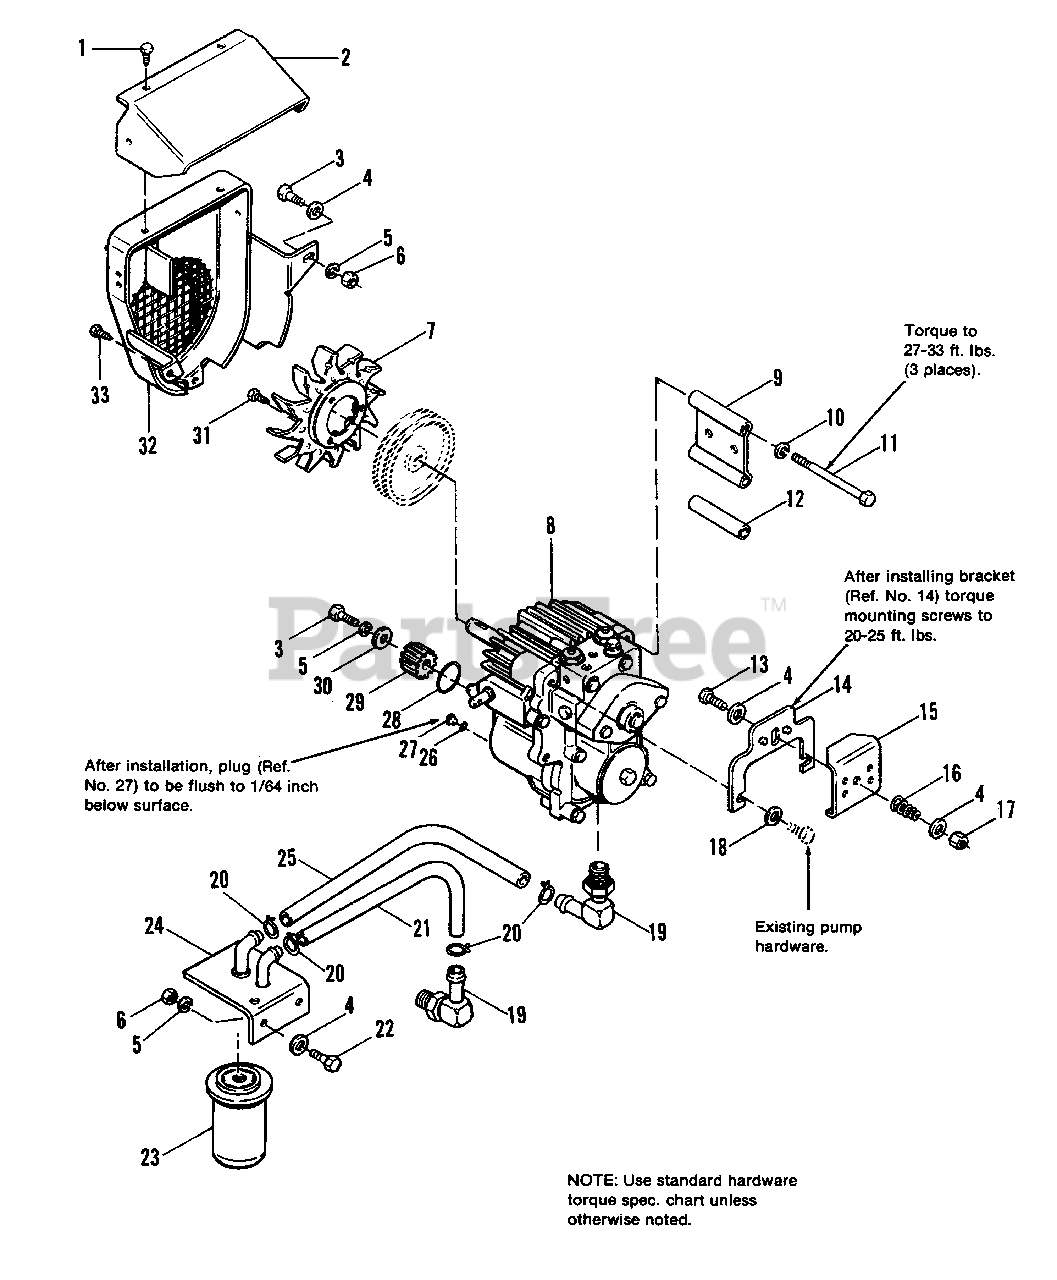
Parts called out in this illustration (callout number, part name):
1	SCREW, Self Tapping, #10 x 3/8
2	DEFLECTOR, Shroud
3	CAPSCREW, Hex Hd., 5/16-18 x 3/4
4	WASHER, Plain, 5/16
5	LOCKWASHER, 5/16
6	NUT, Hex, Full, 5/16-18
7	FAN, Pulley
8	HYDROSTATIC PUMP & MOTOR UNIT (7112 & 7114)
8	HYDROSTATIC PUMP & MOTOR UNIT (7116, 7117 & 7119)
10	LOCKWASHER, 3/8
11	CAPSCREW, Hex Hd., 3/8-16 x 5
12	SPACER
13	CAPSCREW, Hex Hd., 5/16-18 x 1
15	LATCH, Release
17	LOCKNUT, Hex, 5/16-18
19	FITTING, Hose
20	CLAMP, Hose
22	CAPSCREW, Hex Hd., 5/16-18 x 7/8
23	FILTER ASSY., Long Canister
24	SUPPORT ASSY., Oil Filter
29	PINION, Motor Shaft
31	SCREW, Hex, Washer Hd., Taptite, 1/4-20 x 3/8
32	SHROUD ASSY., w/Screen
33	SCREW, Hex, Washer Hd., Taptite, 5/16-18 x 1/2 (7112 & 7114)
33	SCREW, Hex, Washer Hd., Taptite, 5/16-18 x 3/4 (7116, 7117 & 7119)
